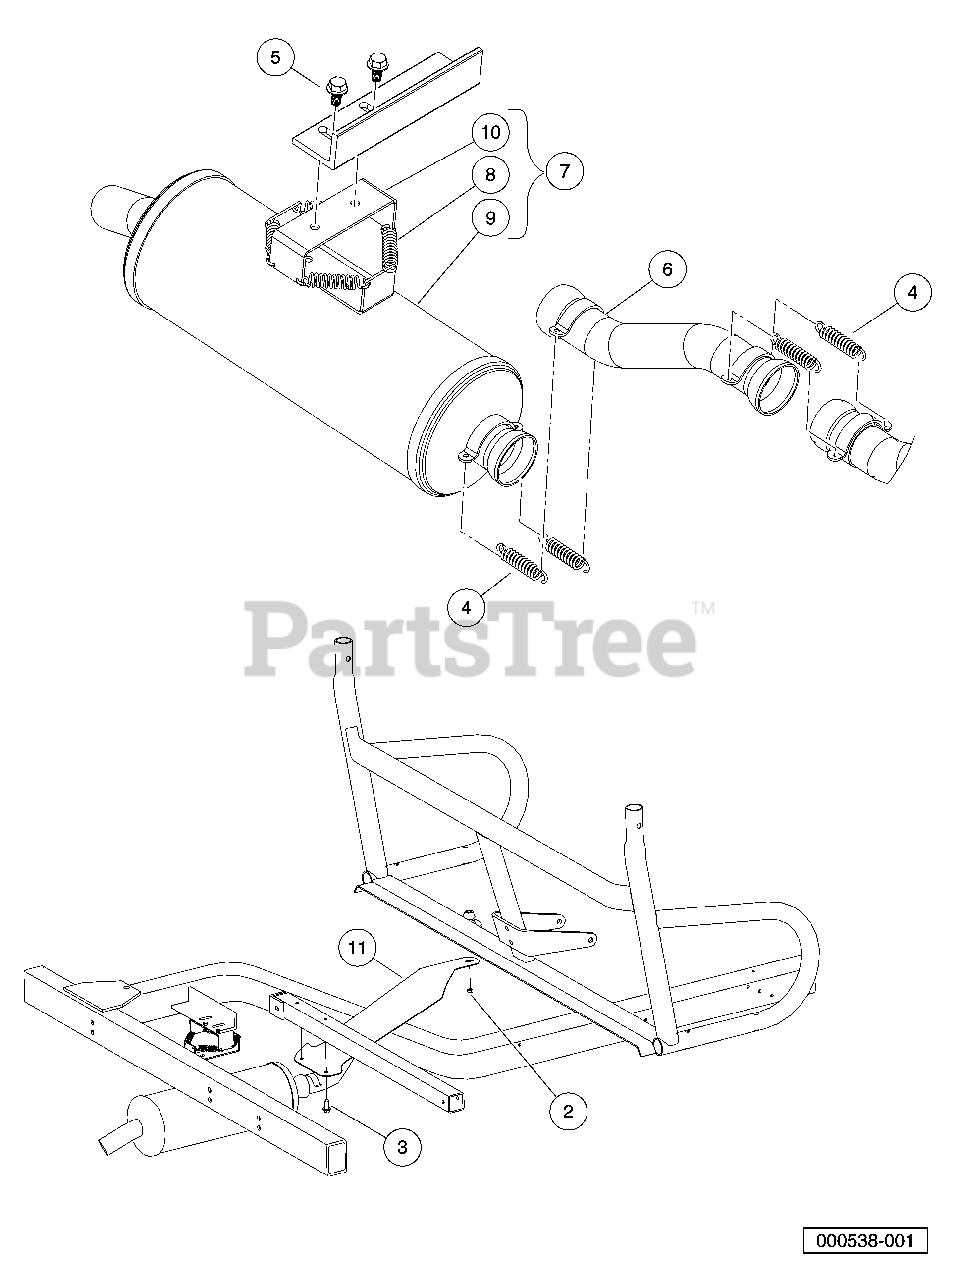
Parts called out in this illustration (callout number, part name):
1	Instl, Exhaust, AWD
2	Locknut, M6-1.00 Nylon Insert
3	M8-1.25x20 Taptite
4	Spring, Exhaust.
5	Bolt Flanged Head, M8 X1.25x 16 with Loctite
6	Pipe, Exhaust, Int, Offset
7	Asm, Muffler, AWD Homologation
8	Spring, Exhaust
9	Muffler.
10	Bracket, Muffler
11	Shield, Exhaust, Clearance
